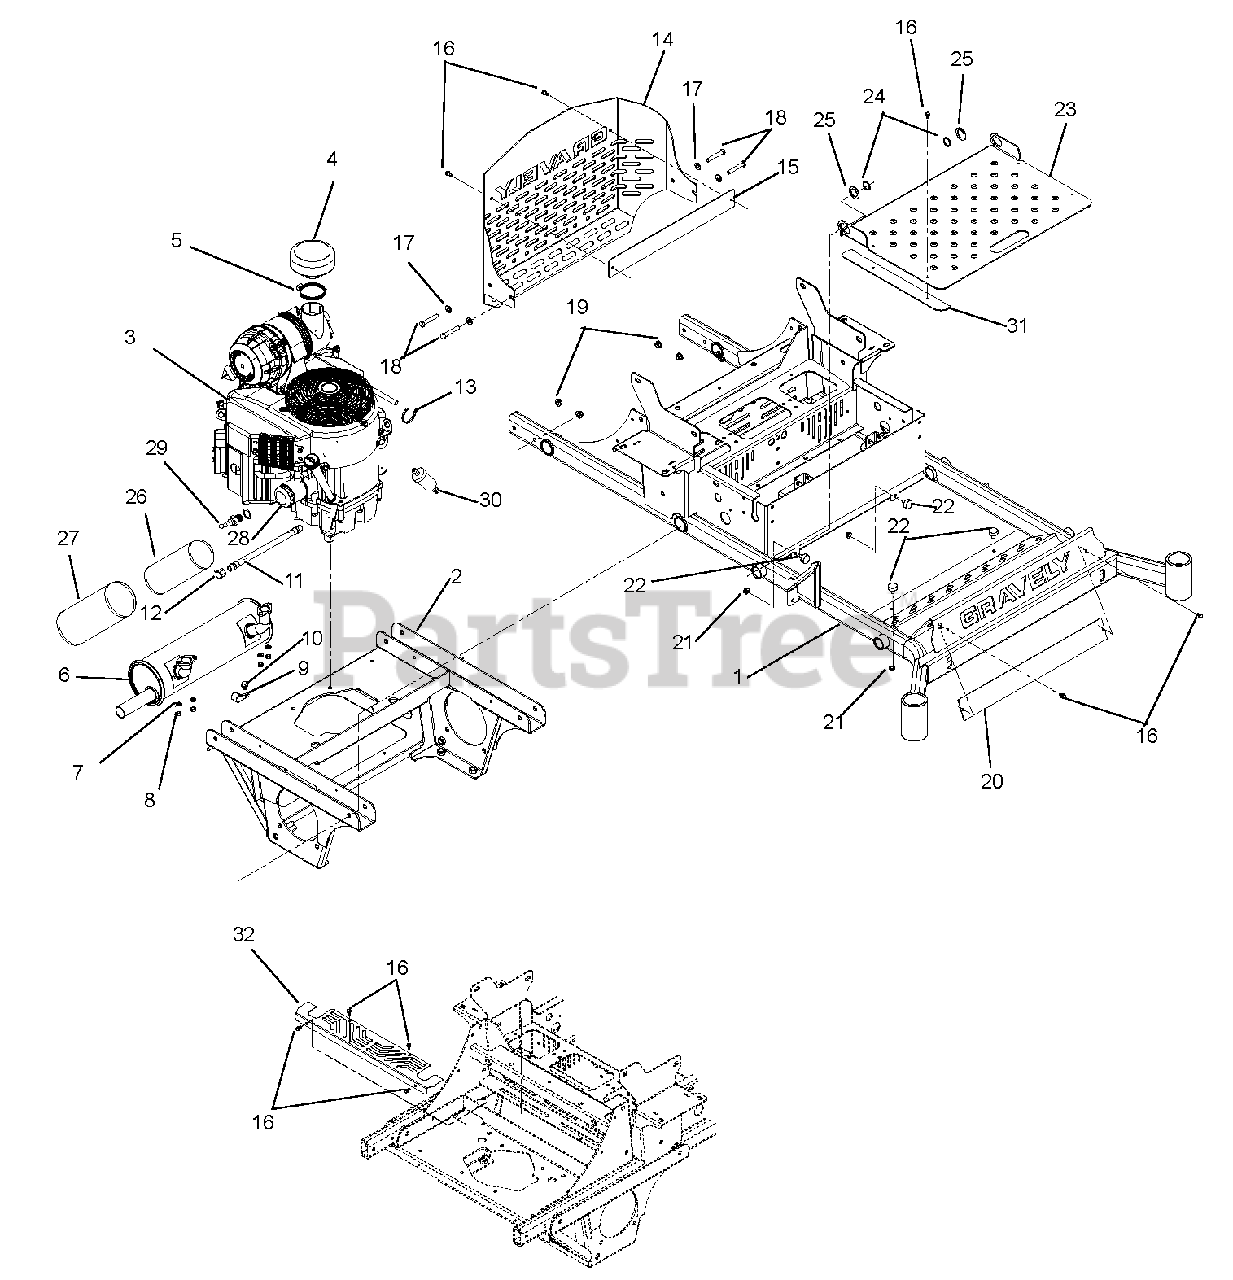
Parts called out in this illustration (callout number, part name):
1	Weldment, 52"-66" 200PT Main Frame
2	Weldment, 200PT Axle/Engine Frame
3	Engine, Kawasaki FX730
4	Rain Cap, Air Cleaner
5	Clamp, Hose 2.75 DIA Worm
6	Muffler, Kawasaki Fixed 24/26HP
7	Washer, Lock .31 x .078 REG YWZC
8	Nut, Locking Top M8-1.25 YWZC
10	Screw, Tap .38-16 x .50 Hex Washer Head TR YWZ
11	Hose, Hydraulic .38-14-0K M6N0-M6N0
12	Pipe Cap 3/8 NPT Female
13	Cable Tie LG 5-1/2
14	Weldment, Bumper, Pro-Turn 200
15	Plate, Bumper, Pro-Turn 200
16	Screw, Tap .25-20 x .50 Hex Washer Head TR YWZ
17	Washer, Flat Steel.406 x .812 x .065 YWZ
18	Bolt, Hex .38-16 x 2.25 GR5 YWZC
19	Nut, Locking Nylon-Flange .38-16 YWZC
20	Plate, Bumper Name Backer
21	Nut, Spin Lock-Flange .312-18
22	Bumper, Rubber
23	Inspection Panel
24	Ring, Retaining, External 1.00 x .078
25	Washer, Flat-Steel 1.010 x 1.505 x .062
26	Element, Inner Safety
27	Element, Outer Primary
28	Oil Filter
29	Spark Plug
30	Fuel Filter
31	Guard, Foot Plate, Finger
32	Guard, CE Rear Access
